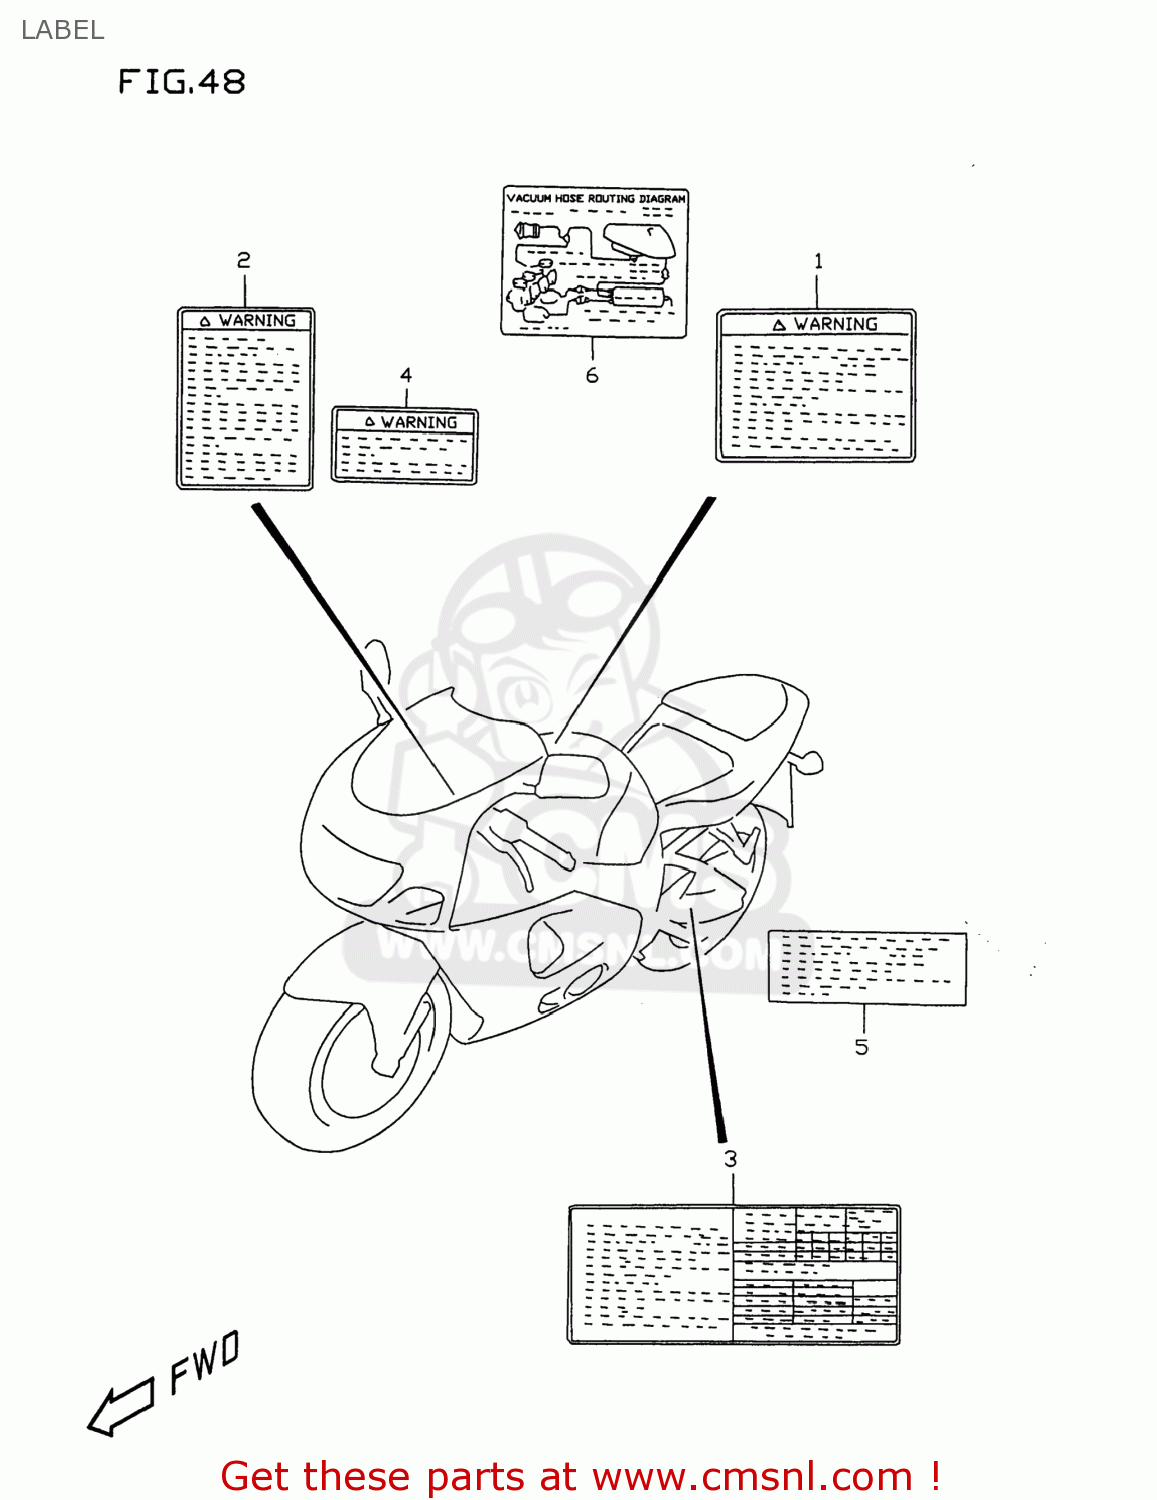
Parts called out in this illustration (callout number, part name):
1	LABEL,WARNING SAFETY
2	LABEL (WARNING SCREEN)
3	LABEL,TIRE INFORMATION
4	LABEL (WARNING)
5	LABEL (MANUAL NOTICE)
6	LABEL,VACUUM HOSE ROUTING
7	MANUAL, OWNER'S
